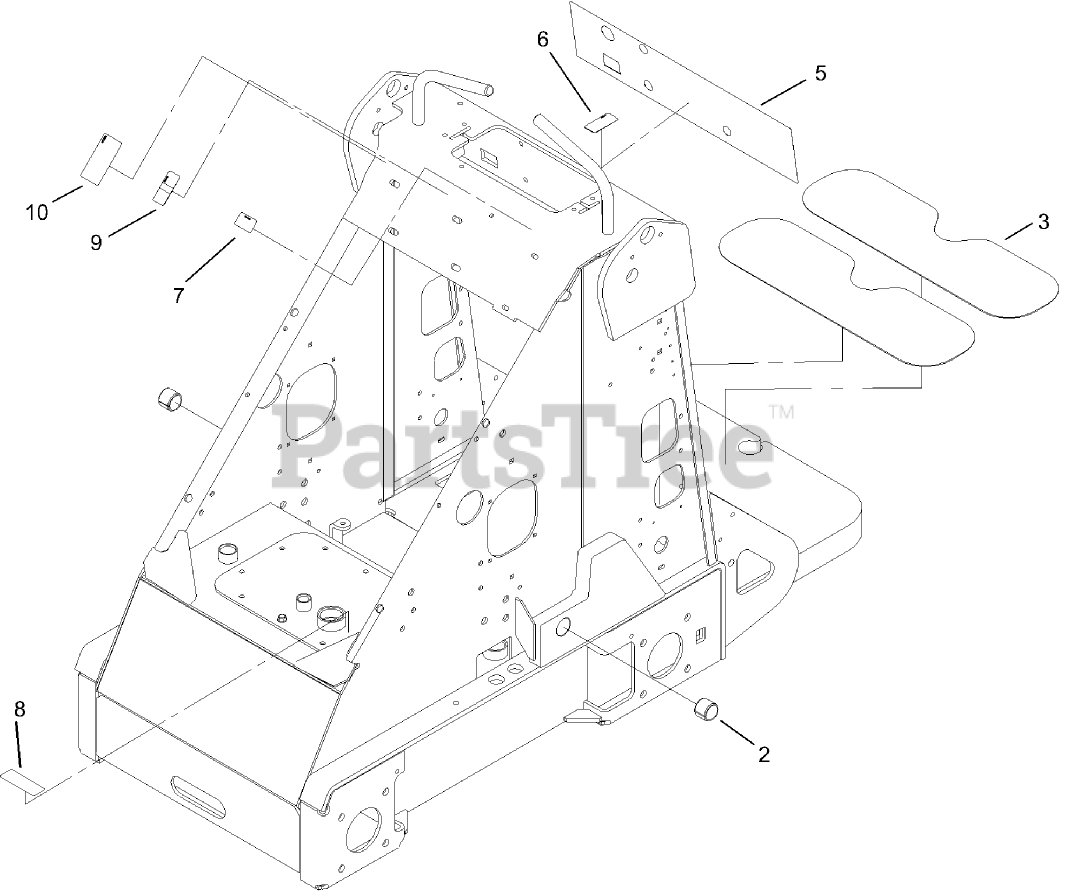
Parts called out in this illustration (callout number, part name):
2	BUSHING-TENSION
3	TREAD-FOOT
5	DECAL-PANEL, CONTROL
6	DECAL-THROTTLE
7	DECAL-LIMITER, SPEED
8	DECAL-OIL, HYD
9	DECAL-SELECTOR
10	DECAL-POWER, AUXILIARY
